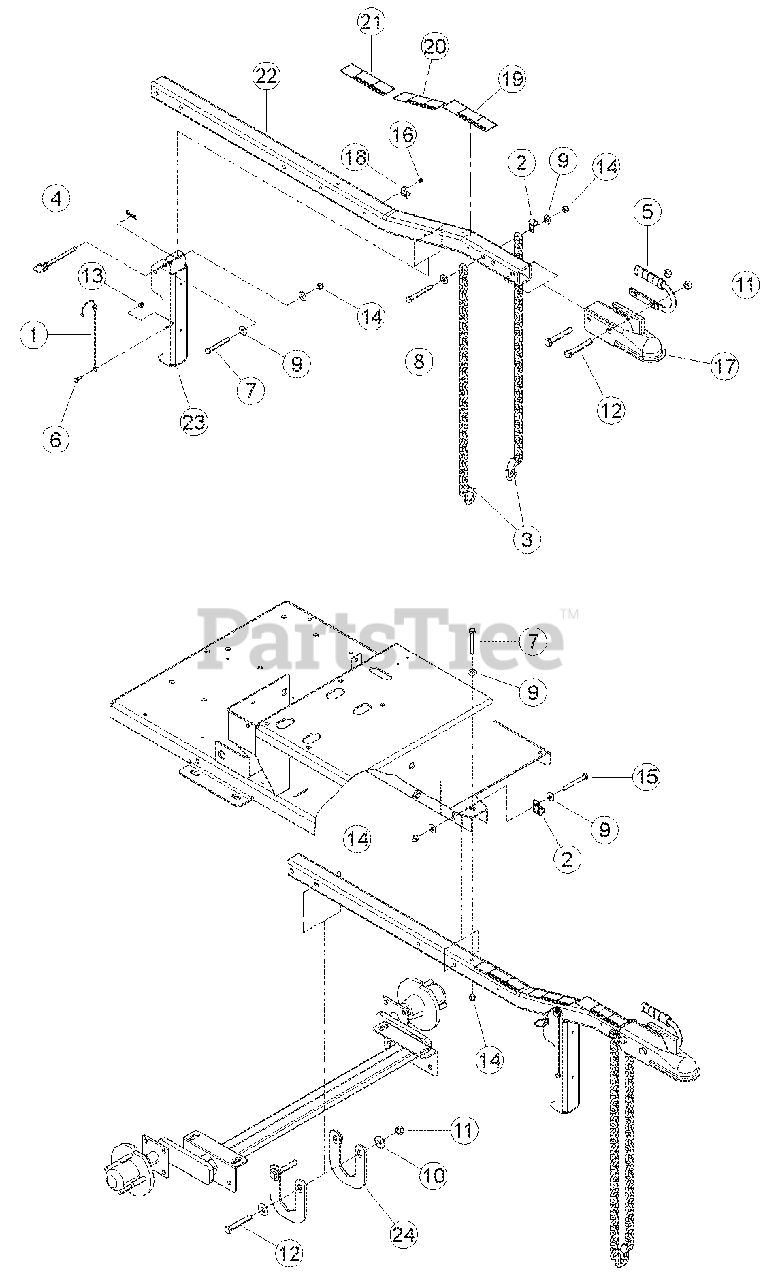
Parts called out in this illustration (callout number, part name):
1	LANYARD, NYLON
2	CLAMP, 9/16" COATED
3	CHAIN, SAFETY 5000 LB W/LATCH
4	PIN, 3/8 HITCH
5	HANDLE, HITCH COUPLER
6	BOLT, 1/4 X 3/4 GR5 HEX HD ZP
7	BOLT, 3/8 X 3 HEX HD GR5 ZP
8	BOLT, 3/8 X 3-1/2 HEX HD GR5 ZP
9	WASHER, 3/8 FLAT ZP
10	WASHER, 1/2 FLAT ZP
11	NUT, 1/2 CENTERLOCK GRB ZP
12	BOLT, 1/2 X 3-1/4 HEX HD GR5 ZP
13	NUT, 1/4 NE NYLOCK ZP
14	NUT, 3/8 NE NYLOCK ZP
15	BOLT, 3/8 X 3-1/4 HEX HD GR5 ZP
16	RIVET, 1/4 X 1/2 AL BLIND DOME HEAD
17	TRAILER HITCH COUPLER
18	CLAMP, CABLE MOUNT
19	DECAL, SAFETY CHAINS
20	DECAL, TRAILER ELECTRICAL
21	DECAL, SAFE COUPLING
22	POLE, C/S HITCH
23	STAND, JACK
24	PLATE, HITCH
